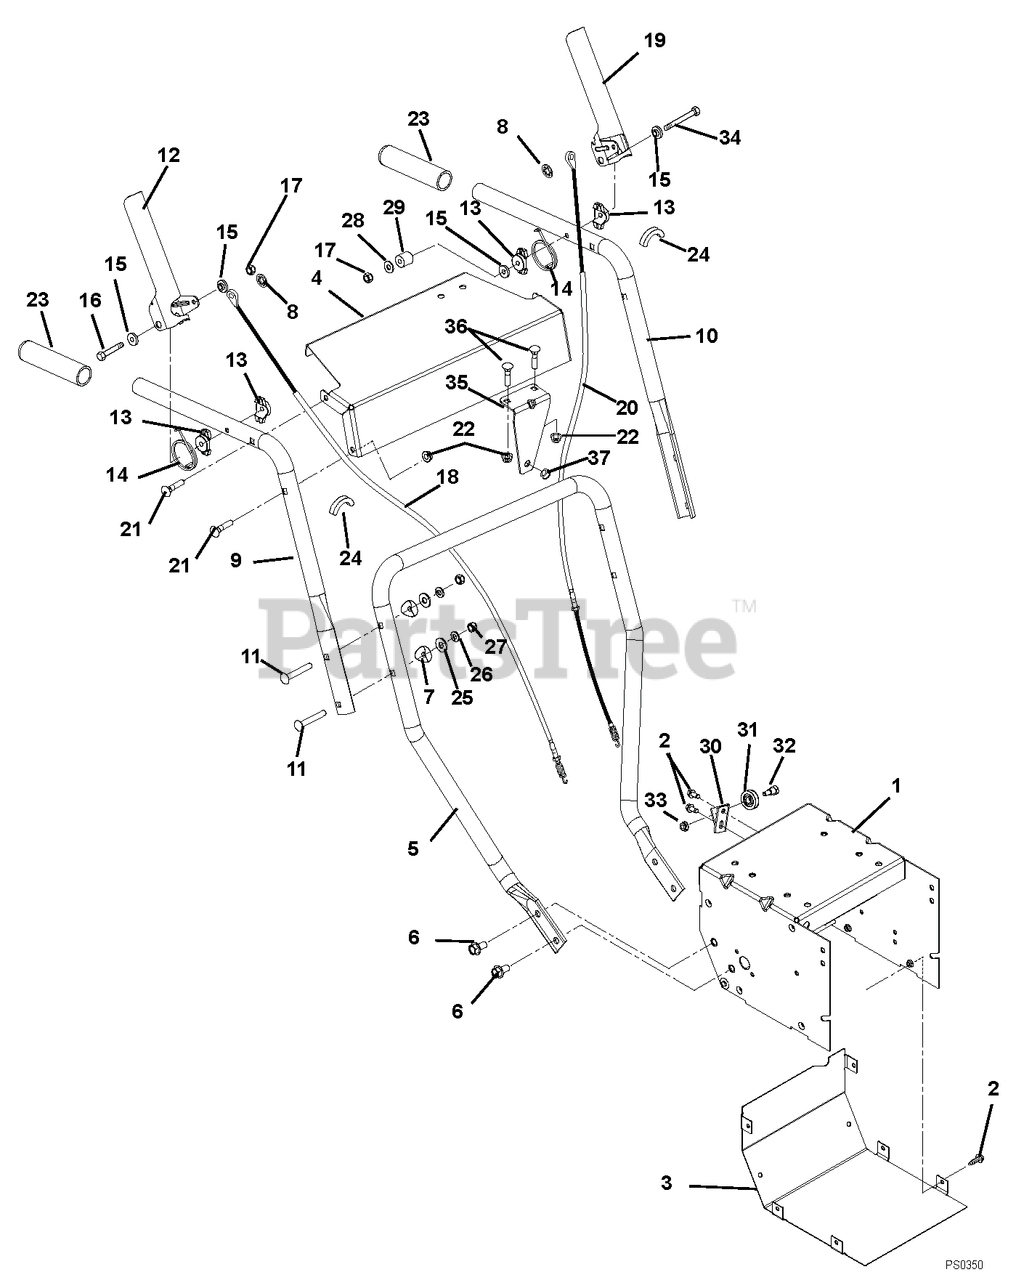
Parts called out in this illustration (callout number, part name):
1	FRAME, WELDMENT
2	@SCR-TAP .25-20X.50 HWH TR YWZ
3	COVER, BOTTOM
4	CONTROL PANEL W/DECAL
5	HANDLEBAR, LOWER (SNGLE SPEED)
6	BLT-SERHFWH .38-16X.75 YWZC
7	SPACER, HANDLEBAR
8	RG-RTNG-EXT .250X.010
9	HANDLEBAR, UPPER RH
10	HANDLEBAR, UPPER LH
11	@BLT-RDHDSQNK .31-18X2.25 G5YZ
12	PADDLE, CLUTCH - RH COMPACT
13	SPACER, HANDLEBAR
14	SPRING, TORSION
15	BSHG, FLG .266X.42X.150 PM
16	@BLT-HEX .25-20X2.50 GR5 YWZC
17	NUT-JAM-NYL .250-20 W/INSERTYZ
18	AUGER CABLE, ST520 SINGLE SPD
19	PADDLE, CLUTCH - LH COMPACT
20	CABLE, TRACTION
21	BLT-RDHDXLSQNK .31-18X1.5 G5YZ
22	@NUT-LK-TOP-FLG .31-18 YWZC
23	HANDLE GRIP
24	EDGING, CLUTCH PADDLE - 2.00"
25	@WSHR-FL-STL.38X.875X.083 YWZC
26	@WSHR-LK .31X.078 REG YWZC
27	@NUT-LK-NYL .312-18 YWZC
28	@WSHR-FL-STL.281X.62X.065 YWZC
29	BSHG, SLV .266 X .750 X .750
30	BRACKET, CABLE PULLEY
31	PULLEY, CABLE
32	BOLT, SHLDR-.375X.375X.25-20
33	@NUT-LK-TOP-FLG .25-20 YWZC
34	@BLT-HEX .25-20X3.25 YWZC
35	MOUNT, SNOTK/SNGLSPD CHUT CRNK
36	@BLT-RDHDSQNK .31-18X.75 G5YZ
37	BUSHING, POLYLINER-.38 SNAPIN
